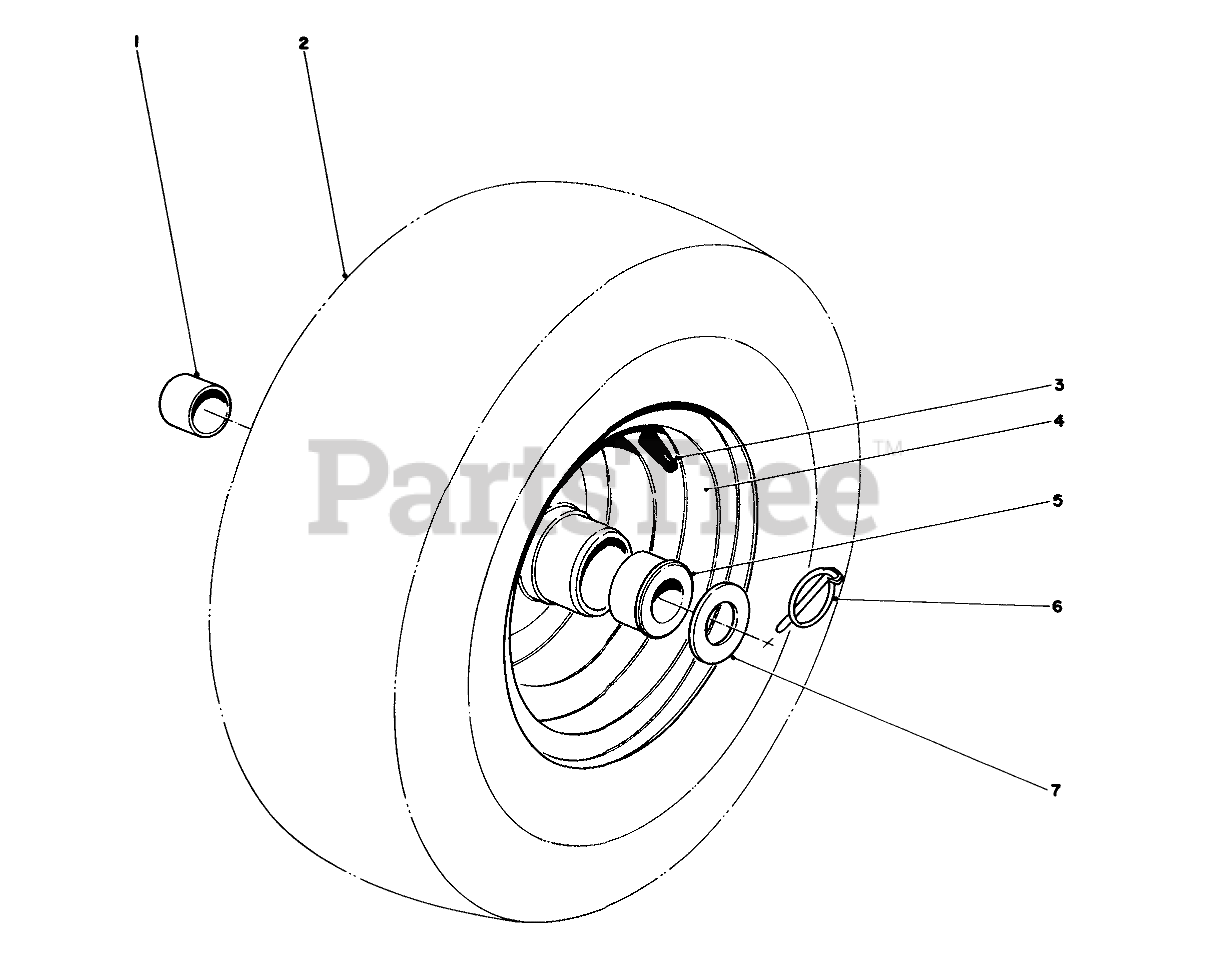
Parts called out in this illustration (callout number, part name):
1	.877ID X .750LG BSHG
2	Tire
3	STEM-VALVE
4	Wheel & Hub Assembly (Incl. Ref. #1 & 5)
5	BUSHING
6	PIN-LYNCH
7	WASHER-THRUST
